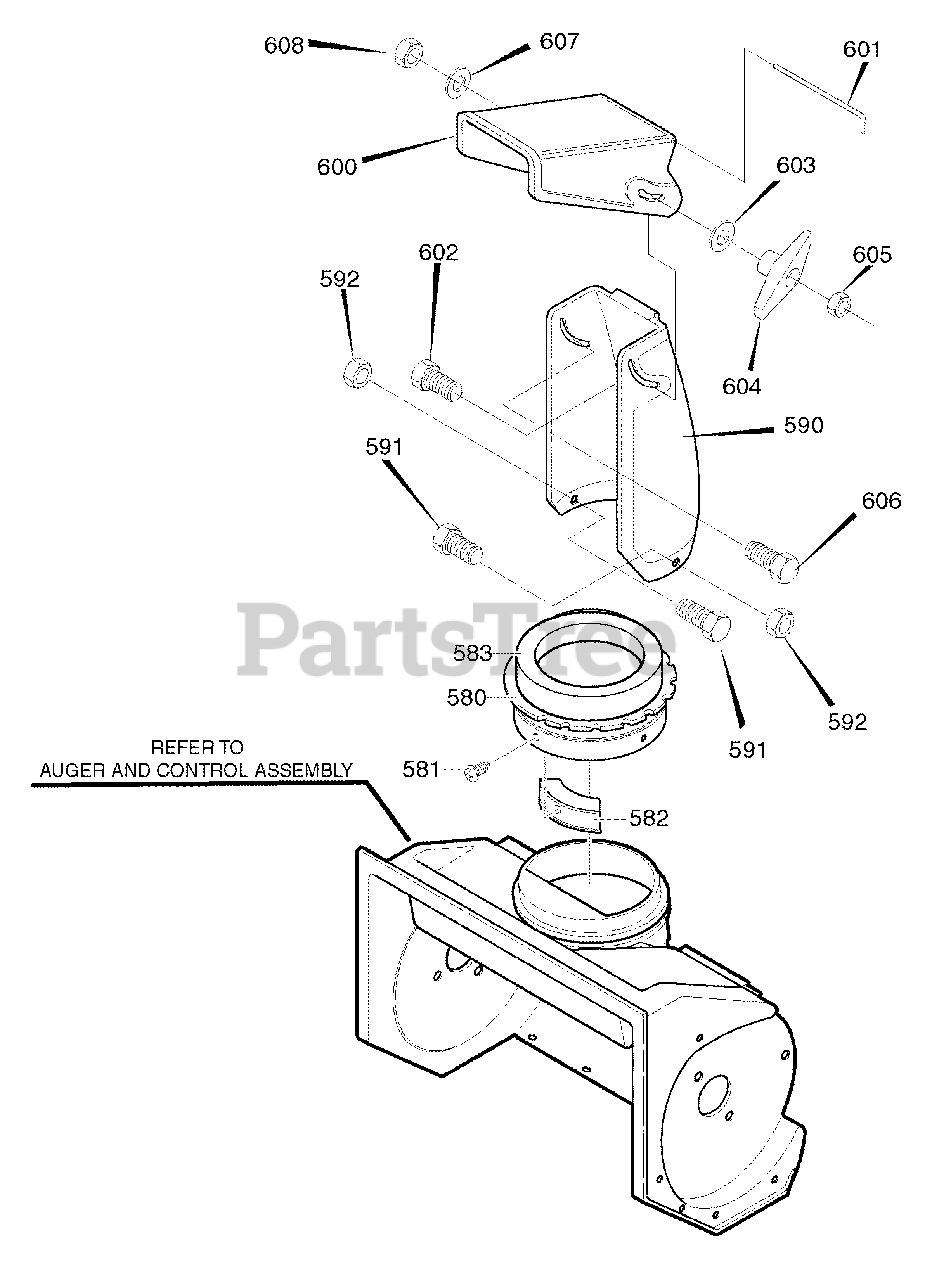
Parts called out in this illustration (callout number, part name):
580	RING, Chute
581	SCREW, #10 x 1/2
582	GUIDE, Chute
583	DONUT, Foam
590	CHUTE, Deflector, Lower
591	CAPSCREW, Hex Head, 1/4-20 x 1/2
592	NUT, 1/4-20
600	CHUTE, Deflector, Upper
601	WIRE, Chute Hinge
602	BOLT, Carriage, 5/16-18 x 1-1/4
603	WASHER, Flat 11/32 x 11/16
604	KNOB, Wing, 5/16-18
605	NUT, 5/16-18
606	SCREW, 5/16-18 x 3/4
607	WASHER, Flat, 11/32 x 11/16 OD
608	NUT, Hex, Control Lock, 5/16-18
